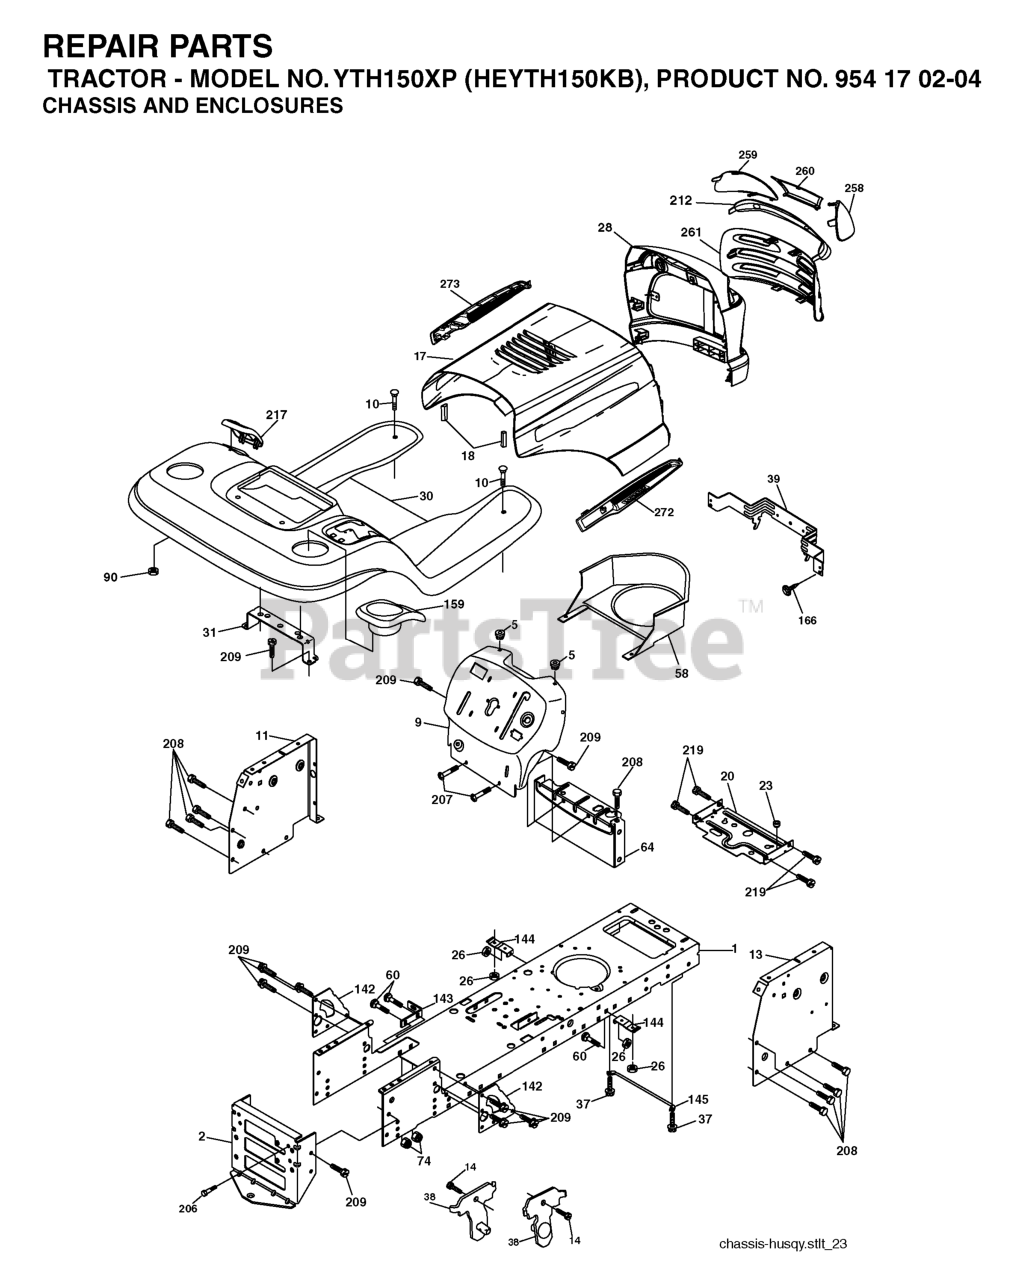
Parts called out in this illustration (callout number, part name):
1	CHASSIS STAMPING
2	DRAWBAR, 12GA
3	SCREW 3/8-16X3/4
5	BUMPER.RUBBER.HOOD
9	DASH
10	BOLT D
11	PANEL.DASH.LH.LTX
13	PANEL ASM, DASH RH
17	VENT.HOOD.LASER.III
18	BUMPER.HOOD.LARGE.1.75"
20	PLATE MTG.BATTERY/FUEL TANK
23	BUSHING.SNAP.NYL.BLK.
26	NUT
30	FENDER
31	BRACKET.SUPPORT.FENDER
37	Screw 5/16-18 x 1/2 Hex, Self Tapping 5/16-18 x 1/2
38	BRACKET.ASM.PIVOT.MOWER.REAR
39	BRACKET PIVOT LASER
60	Bolt - Rd. Hd. Sq. Neckiage 3/8 16 x 3/4
64	DASH LOWER
90	NUT.PUSH.3/16
142	PLATE REINFORCEMENT
143	BRACKET, SWAYBAR CHASSIS
144	BRKT, FOOT REST
145	ROD PIVOT CHASSIS/HOOD
159	GREY CUP HOLDER
166	SCREW
206	SHOULDER BOLT 5/16-18TT
207	SCREW, 5/16-18 X 1/2
208	SCREW 3/8-16X1/2
209	SCREW, 3/8-16X3/4
212	INSERT.LENS.REFLECTIVE
217	CONSOLE FUEL WINDOW
219	SCREW
258	LENS LH
259	LENS LH
260	COVER.LENS.HUSQ.LASER
272	VENT.HOOD.LASER.
273	VENT.HOOD.LASER.
